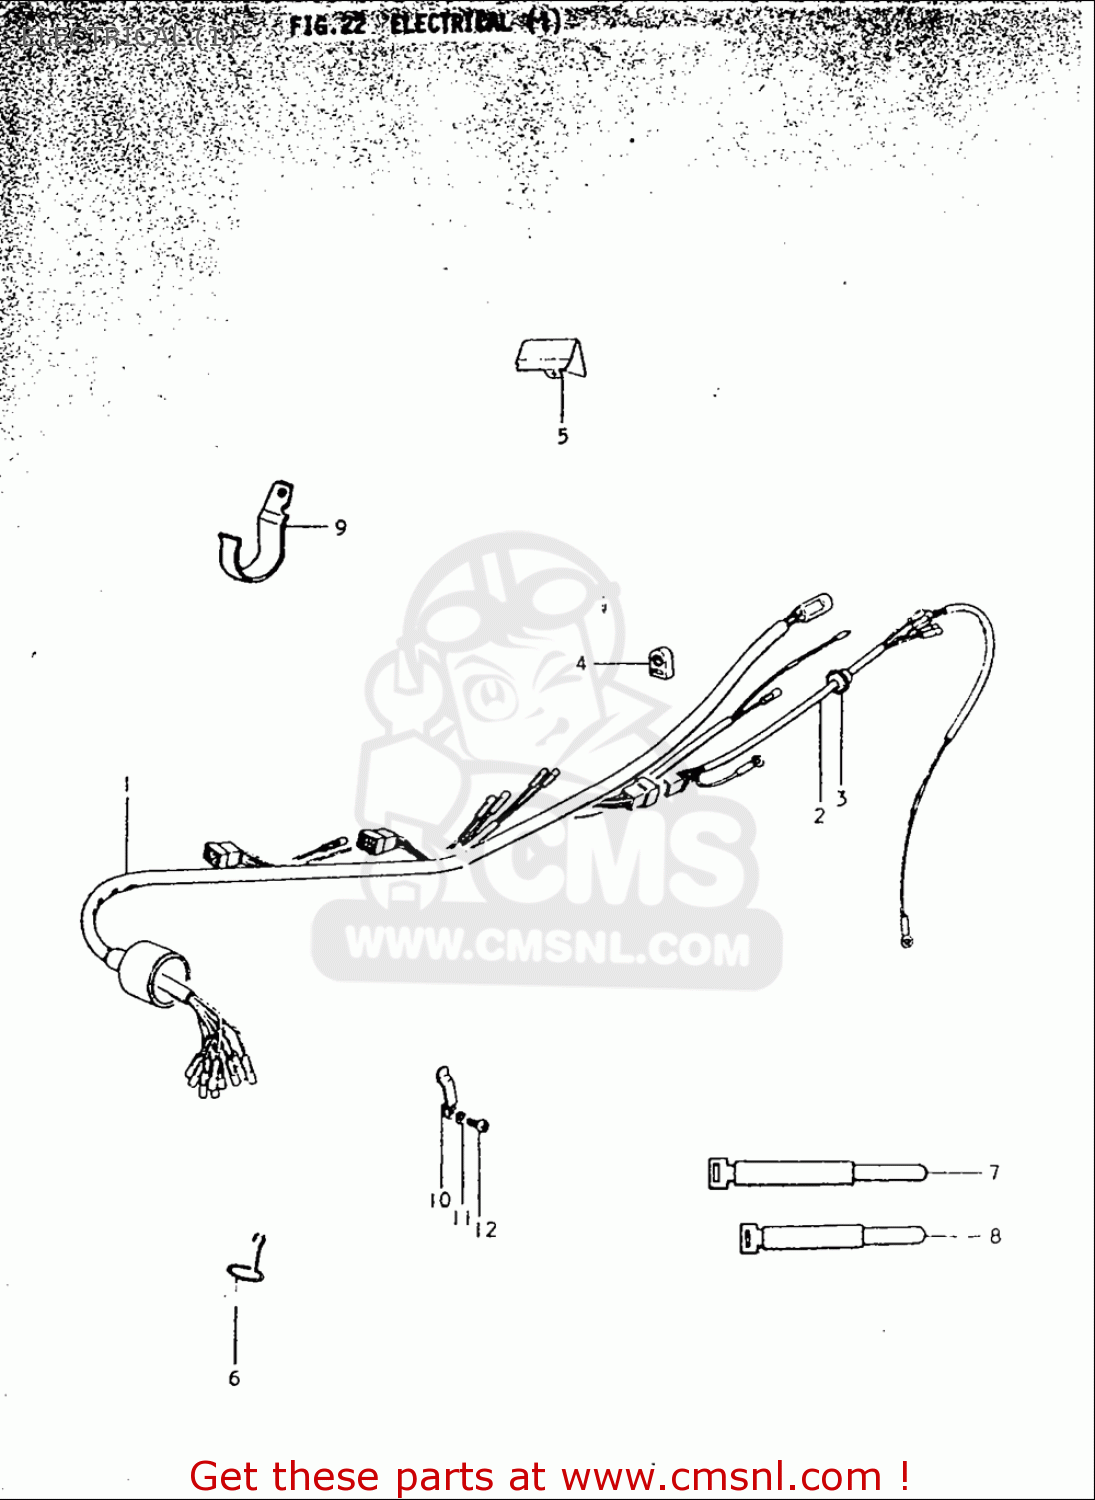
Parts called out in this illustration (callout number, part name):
10	CLAMP
11	WASHER,LOCK
12	SCREW
